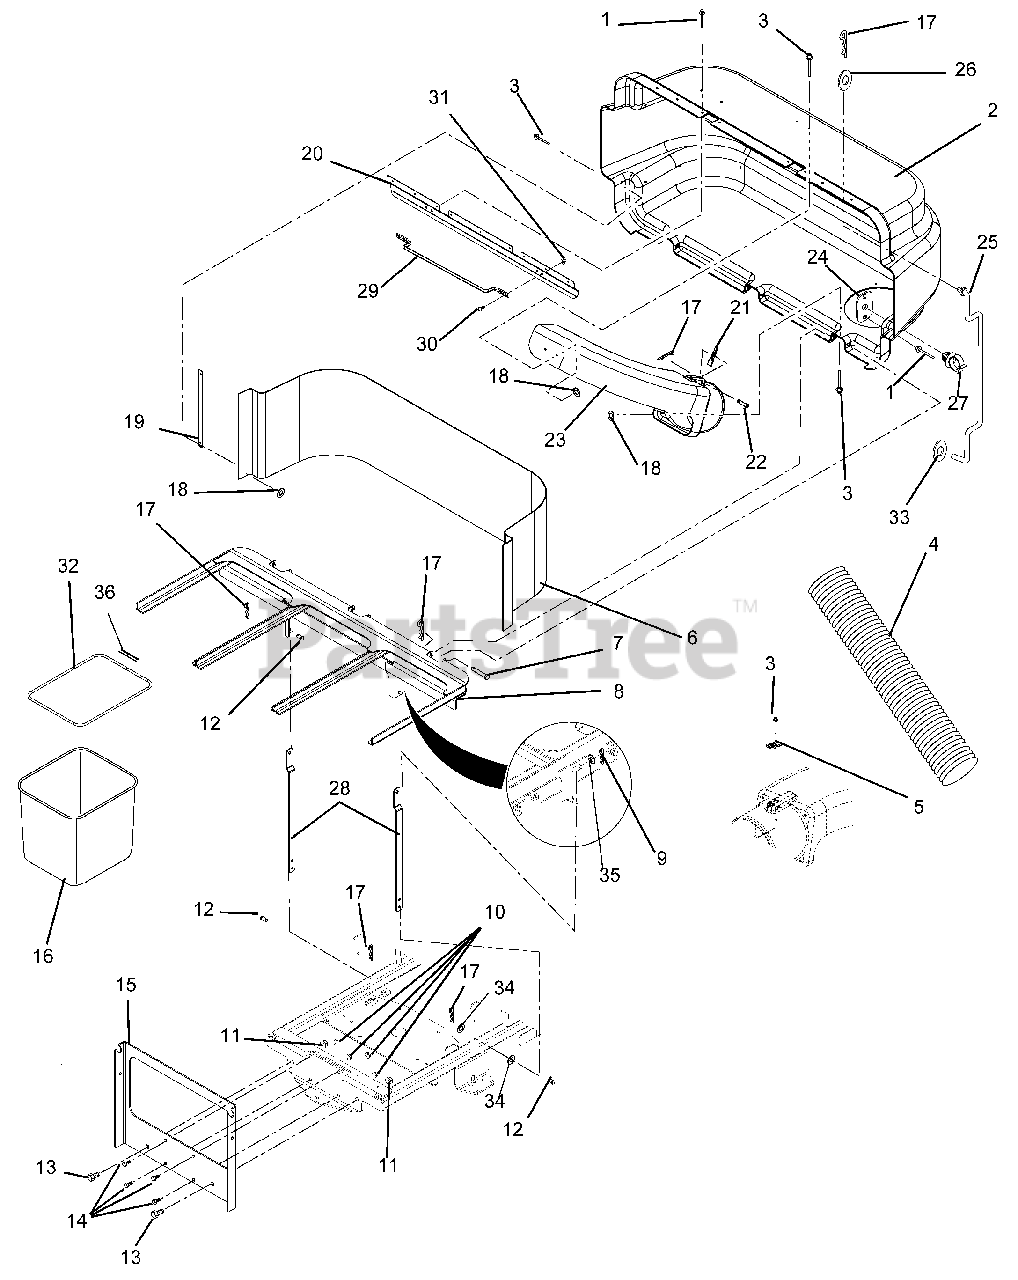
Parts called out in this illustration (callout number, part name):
1	Rivet-Pop .187 x .402
2	Cover, Bagger with Decal
3	Rivet-Pop .187 x .375
4	Hose, 7 x 38 Kanaflex 165 Clear
5	Thumb Latch
6	Screen, Bagger
7	Pin-Clevis .368/.373 x 3.25
8	Weldment, Bagger Frame
9	Pin, Hair, External- #16
10	Nut, .38-16 Nyloc Flange
11	Nut, .50-13 Nyloc Flange
12	Pin, Clevis .38 x .75
13	Bolt, Hex .50-13 x 1.00 Grade 5
14	Bolt, Hex .38-16 x 1.00 Grade 5
15	Mount, Rear Bagger
16	Bag, Mesh
17	Pin-Hair
18	Washer-Flat-Steel .219 x .50 x .049
19	Strap, Cover
20	Latch, Cover
21	Indicator, Flow
22	Pin-Clevis .31 x 2.62 Grade 5
23	Boot, Upper
24	Plate, Rod Clip
25	Prop-Rod, Bagger
26	Washer-Flat-Steel .046 x .812 x .065
27	Clip .38
28	Strap, Reinforcing
29	Bagger Handle
30	Bolt, Round Head Square Neck .25-20 x .75 Grade 5
31	Nut, Locking-Top-Flange .25-20
32	Frame, Bag
33	Retainer, .38 Push-On
34	Washer, Flat-Steel .38 x .875 x .083
35	Washer, Flat-Steel .505 x 1.00 x .062
36	Hose, .38 x .50 x 3.00 Vinyl
